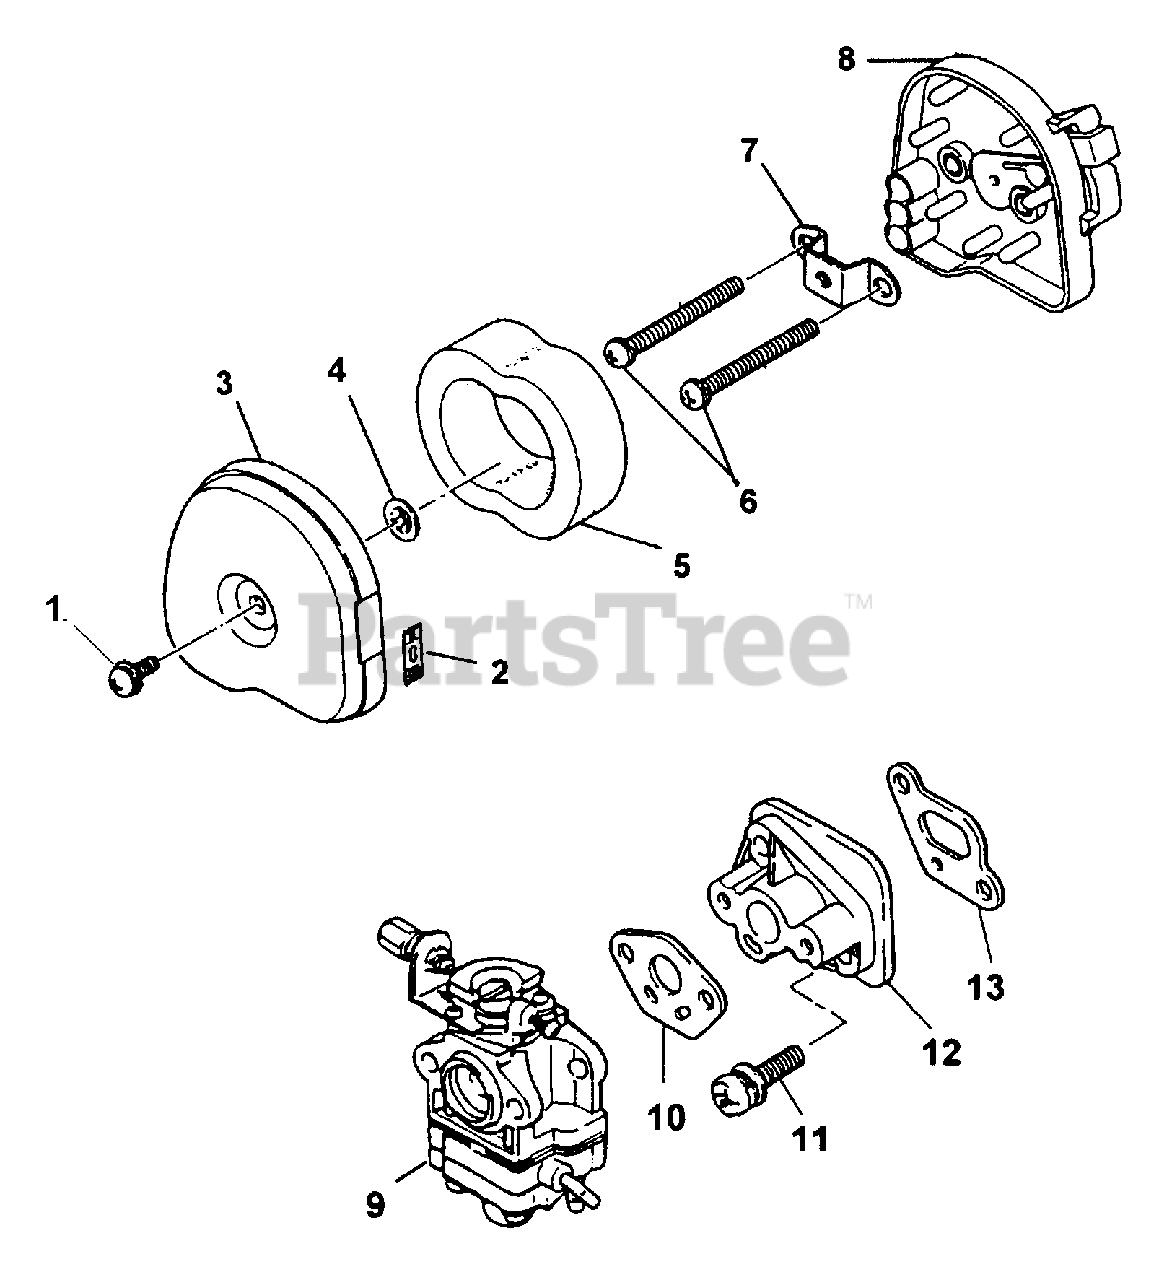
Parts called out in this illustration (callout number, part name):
1	SCREW & WASHER
2	LABEL, CHOKE
5	ELEMENT
6	SCREW & WASHER
7	BRACKET
9	CARBURETOR
10	GASKET, CARB
11	SCREW & WASHER
12	INSULATOR
13	GASKET, INSULATOR
